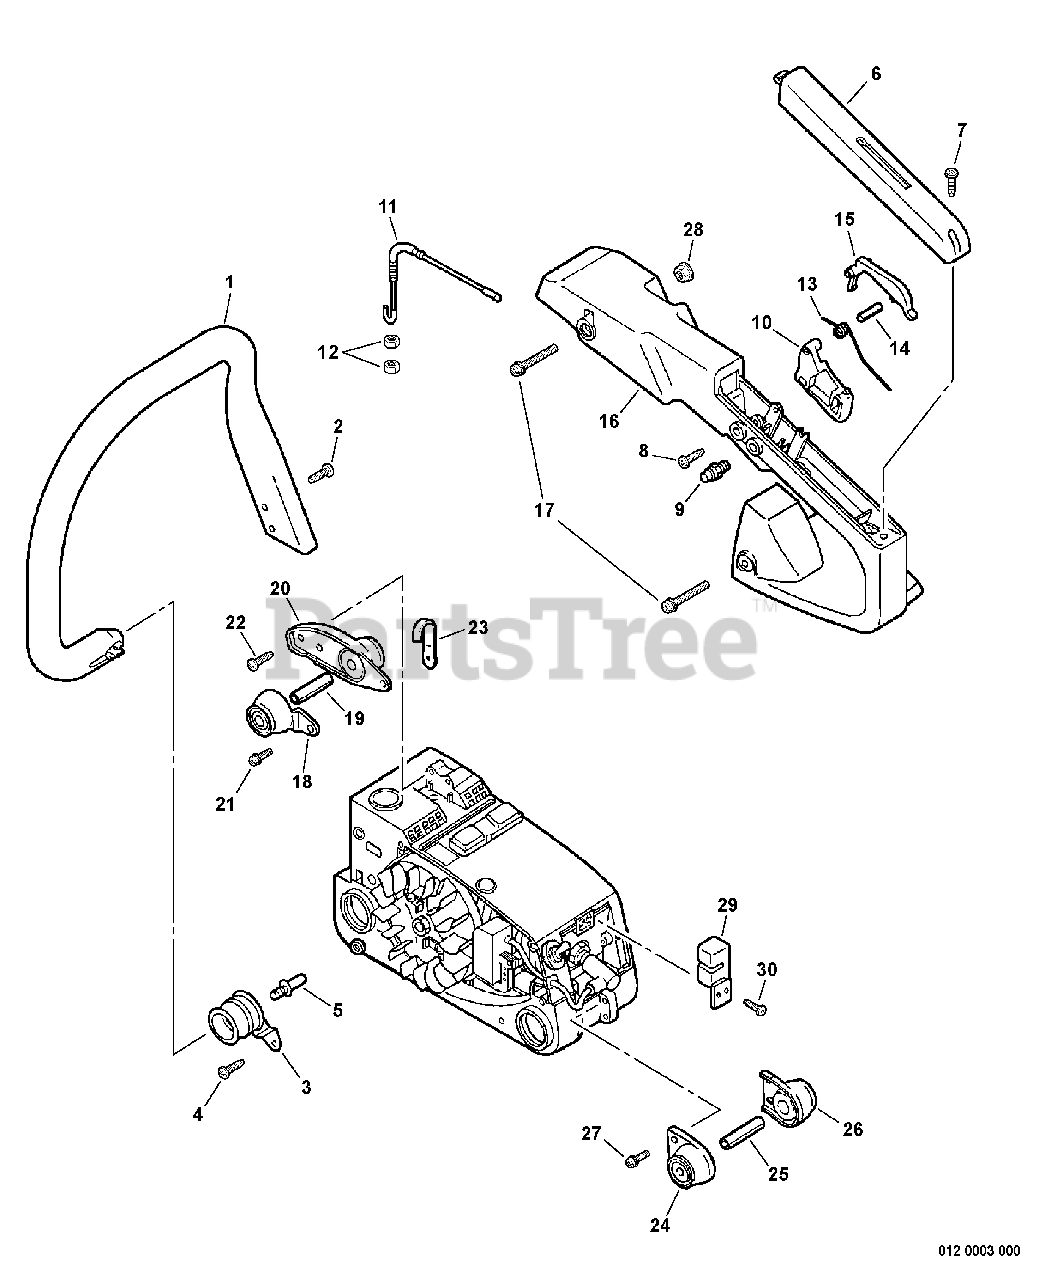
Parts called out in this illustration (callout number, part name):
1	HANDLE - FRONT
2	SCREW - 5X20 -- TAPPING
4	SCREW - 4X16
6	COVER, HANDLE
7	SCREW - 4X22
8	SCREW - 4X25
9	LATCH, THROTTLE
10	TRIGGER, THROTTLE
11	CABLE, THROTTLE
14	ROLLER - 4X19.8
15	LOCKOUT, THROTTLE
16	HANDLE - REAR
17	SCREW - 5X57
18	CUSHION - UPPER
19	COLLAR - 6
20	CUSHION - UPPER
21	SCREW - 4X10
22	SCREW - 4X14
24	CUSHION - LOWER
25	COLLAR - 6
26	CUSHION - LOWER
27	SCREW - 4X14
28	NUT - 5 -- FLANGE
30	SCREW - 4X14
